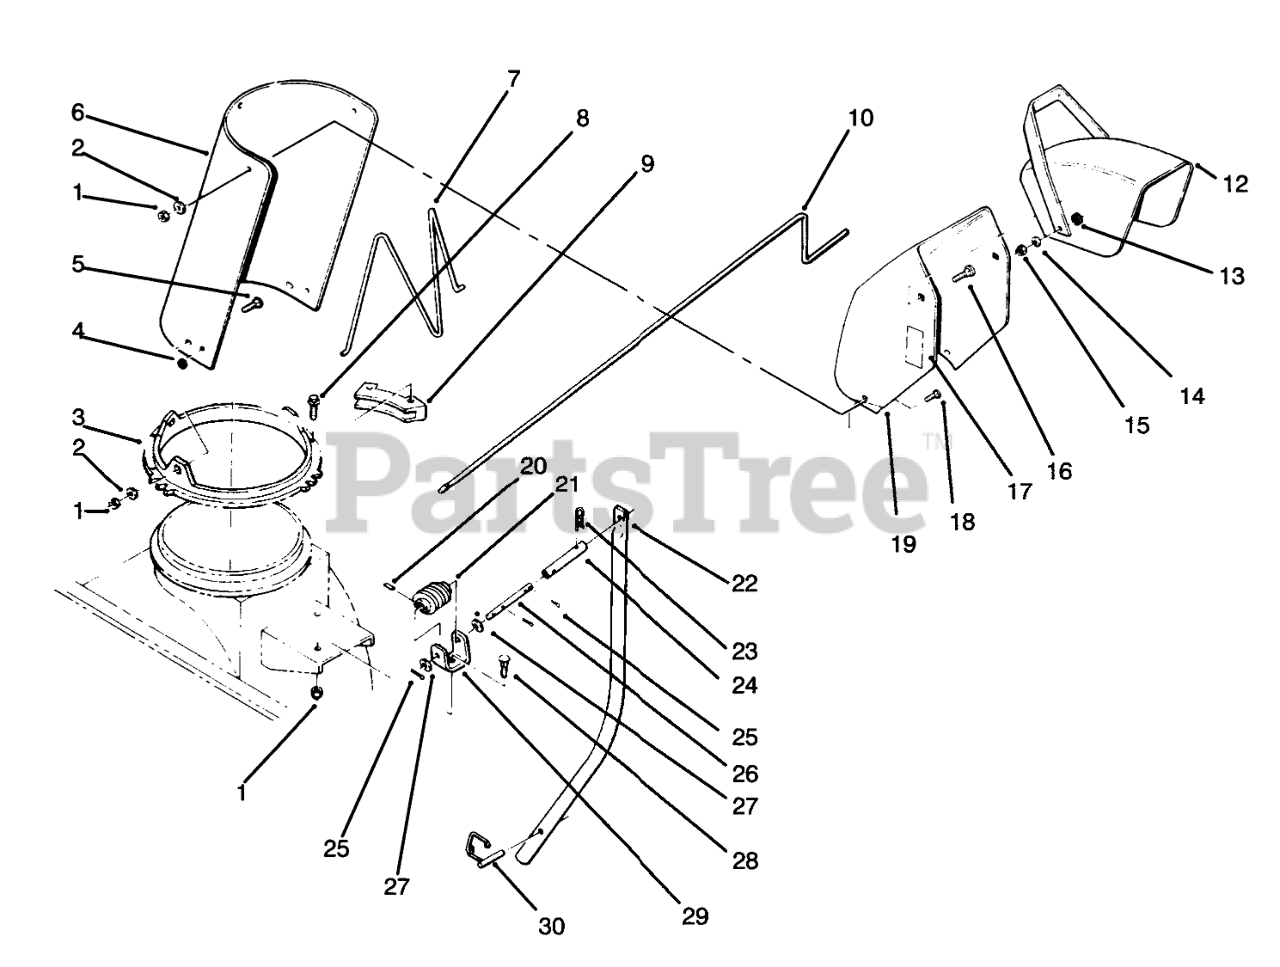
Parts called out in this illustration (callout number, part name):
1	NUT-LOCK, NI
2	WASHER-PLAIN
3	Screw
4	NUT-PUSH
5	SCREW-CARR
6	EXTENDER-CHUTE, UPPER
7	WIRE-CHUTE
8	SCREW-SPECIAL
9	RETAINER-CHUTE
10	ROD-CHUTE CONTROL
12	Deflector
13	WASHER-RUBBER
14	WASHER-BELLEVILLE
15	NUT-LOCK, NI
16	BOLT-CARR
17	Decal-Danger
18	SCREW-HH
19	Chute-Upper Discharge (Incl. Ref. #17)
20	PIN-SPRING
21	GEAR-WORM, CHUTE
22	TUBE-CRANK SUPPOR R
23	PIN-HAIR
24	COUPLING
25	PIN-COTTER
26	ROD-LOWER CHUTE CONT
27	WASHER-FLAT
28	BOLT-CARR
29	WORM BRKT B
30	LOCKING PIN ASM
